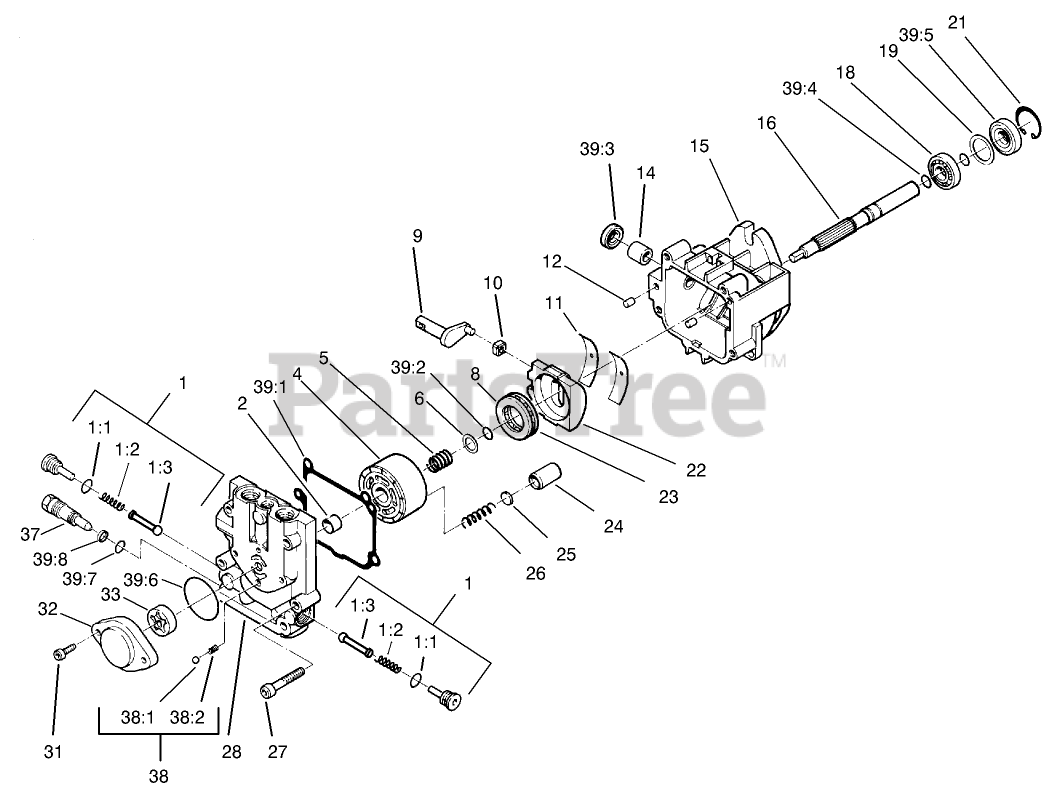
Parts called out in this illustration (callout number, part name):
1	CHECK VALVE KIT
1:1	Seal-Dust
1:2	Spring
1:3	Poppet
2	Journal-Bearing
4	Block-Cylinder
5	Spring
6	Washer
8	Plate-Thrust
9	Arm-Trunion
10	Guide-Slot
11	Cradle-Bearing
12	Pin
14	Journal-Bearing
15	Housing
16	Shaft
18	Bearing-Ball
19	Spacer
21	RING-Retaining
22	Swashplate ASM
23	Roller-Thrust
24	Piston
25	Washer-Thrust
26	Spring-Piston
27	Screw
28	Cap-End
31	Screw
32	Housing-Pump, Charge
33	Gerotor ASM
37	Valve-Bypass
38	RELIEF VALVE CHARGE KIT
38:1	Ball
38:2	Spring
39:1	Gasket-Cap, End
39:2	RING-Retaining
39:3	Seal-Lip
39:4	RING-Retaining
39:5	Seal-Lip
39:6	Seal-Dust
39:7	Seal-Dust
39:8	Ring-Back Up
